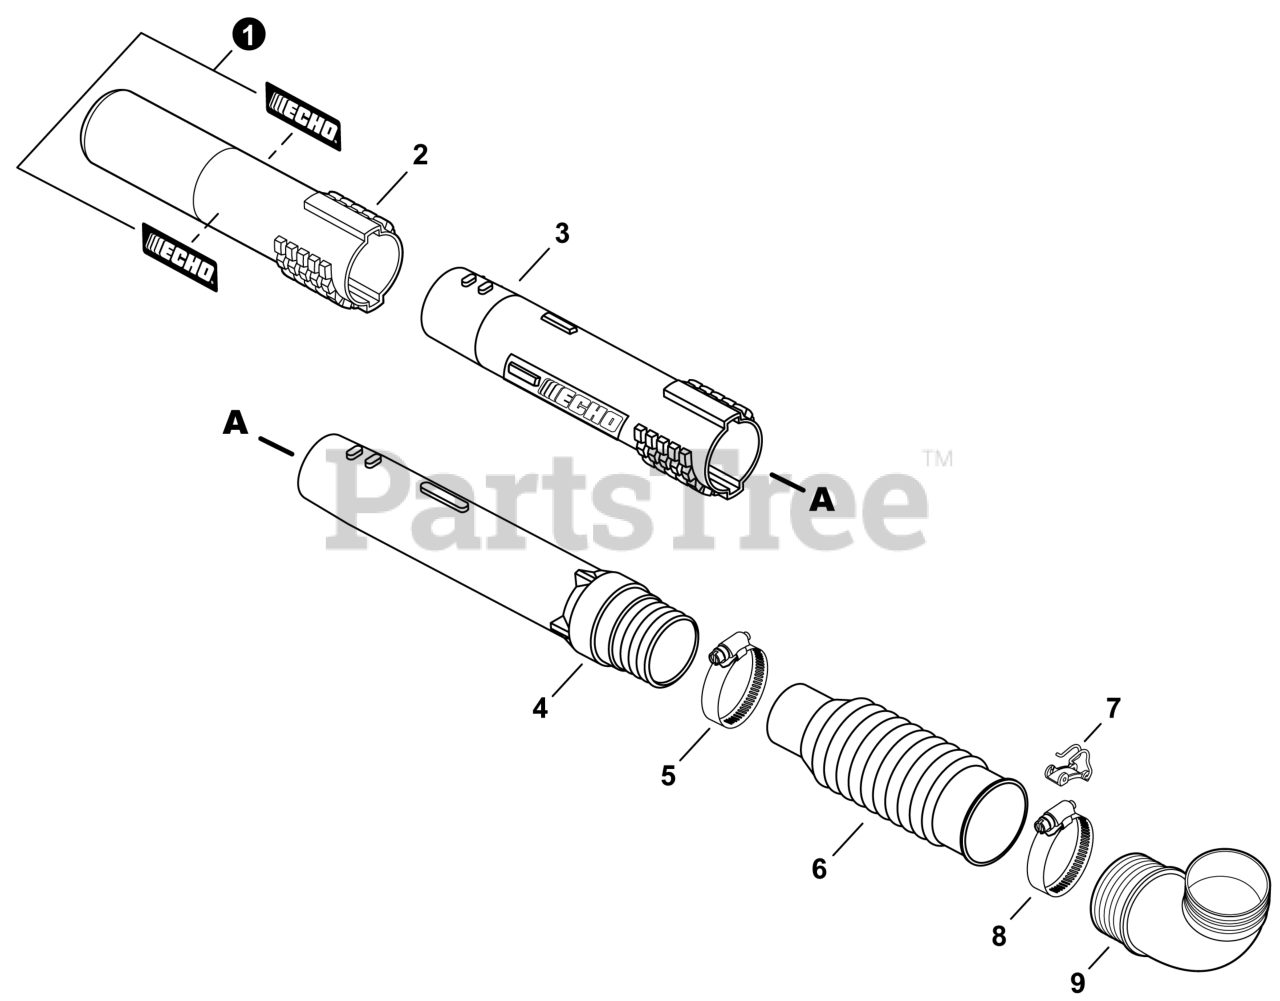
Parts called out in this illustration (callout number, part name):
1	LABEL - ECHO
2	TUBE, BLOWER - NOZZLE
3	TUBE, BLOWER - STRAIGHT
4	TUBE, BLOWER - SWIVEL
5	CLAMP - BAND 58.7 MM / 82.5 MM
6	TUBE, BLOWER - FLEXIBLE
7	CLIP, CABLE
8	CLAMP - BAND 78 MM / 103 MM
9	TUBE, BLOWER - ELBOW
